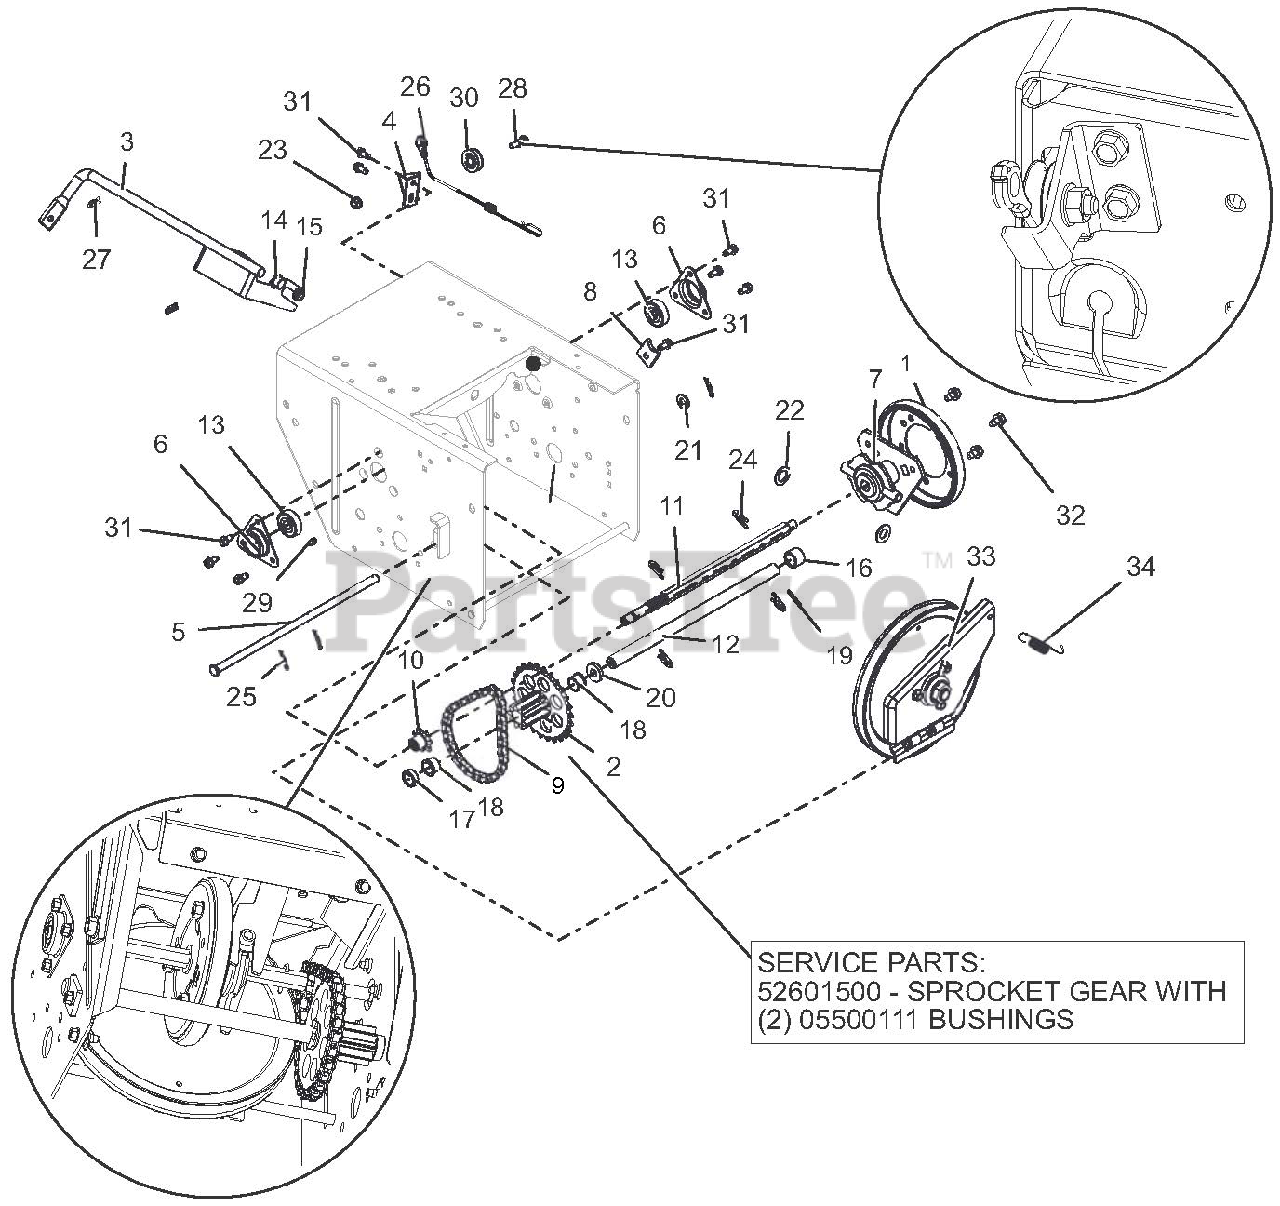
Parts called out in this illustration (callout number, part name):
1	FRICTION, DISC
2	PINION & SPROCKET
2	PINION & SPROCKET W/BUSHINGS
2	BSHG-FLG .625X.750X.500X.875
3	ARM, SHIFT-WELDMENT
4	BRACKET, CABLE PULLEY
5	PIN, PIVOT
6	FLANGE, BEARING
7	CARRIER, DRIVE DISK
8	TAB, ANTI ROTATION
9	CHAIN - #41, 32 PITCHES
10	SPROCKET, PINION 7T W/SPLINE
11	SHAFT, HEX-W/SPLINE TRACK
12	SHAFT, PINION - HARDENED
13	BRG-BALL .437X1.375X.437
14	BUSHING, POLYLINER-.50 SPLIT
15	BUSHING, POLYLINER-.50 SNAPIN
16	SPACER, .635X.880X.611
17	BSHG-SLV, .635X.880X.305
18	BSHG-FLG .625X.750X.500X.875
19	PIN-ROLL .125X1.00
20	WSHR-FL-STL .406X1.00X.188 YWZ
21	@WSHR-FL-STL.406X.812X.065 YWZ
22	WSHR-FL-STL .
23	@NUT-LK-TOP-FLG .25-20 YWZC
24	PIN, SPRING CLIP
25	PIN-HAIR, ENDRIES #25 YWZC
26	CABLE, LOWER TRACTION,SS & PRO
27	CLIP, SPRING
28	BOLT, SHLDR-.375X.375X.25-20
29	ZERK,FITTING .25X.125 DRIVE IN
30	PULLEY, CABLE
31	SCR-TAP .25-20X.50 HWH TR YWZ
32	@SCR-TAP .31-18X.50 HWH TR YWZ
33	PLATE, SWING ASSEMBLY-DEEP
34	SG-TENS .048X.50X2.8
